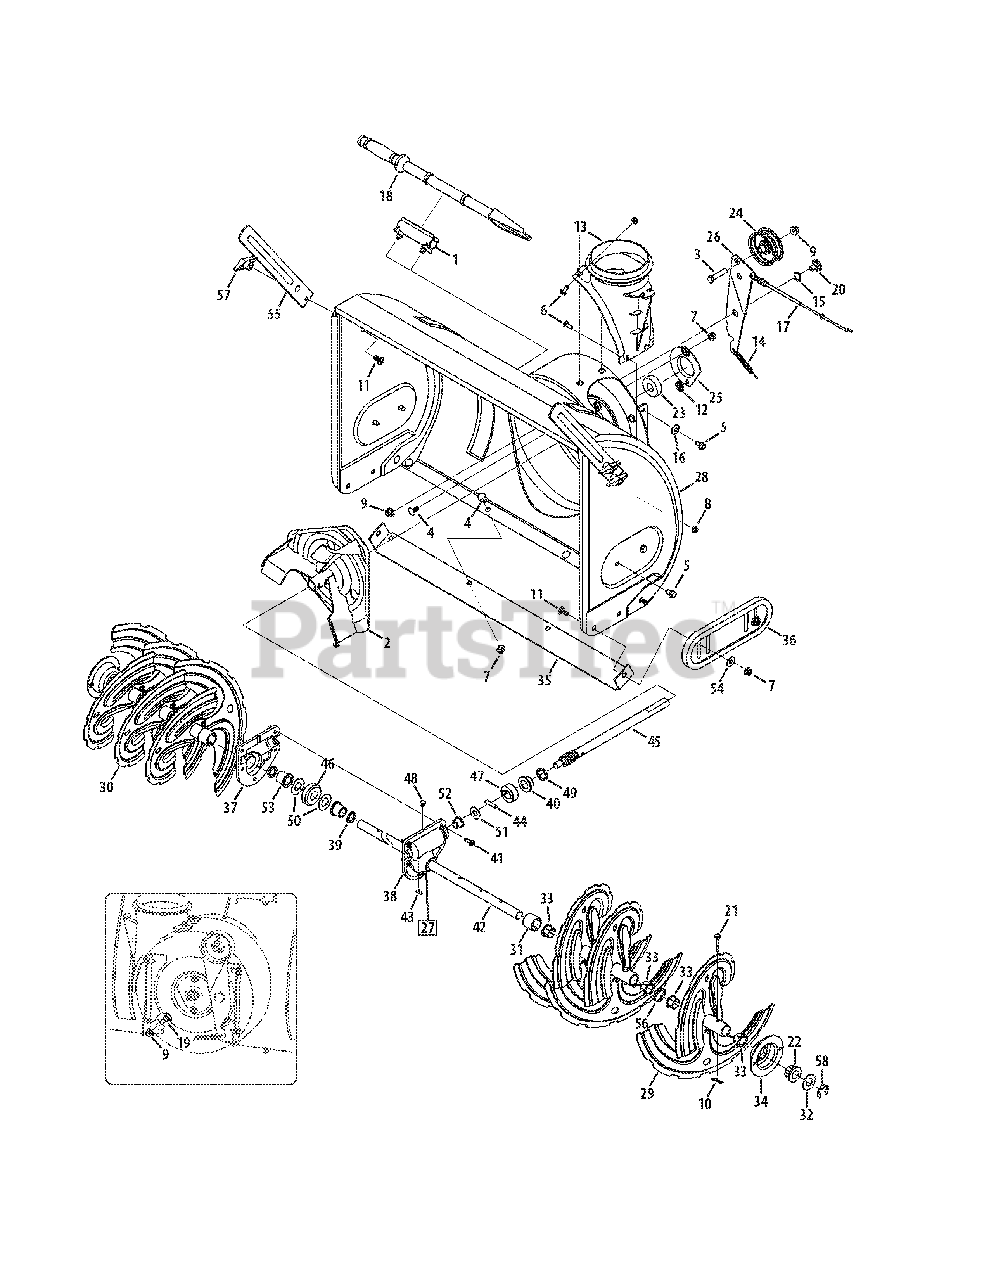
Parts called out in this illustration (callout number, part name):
1	Snow Removal Tool Mount
2	Impeller Assembly, 12" Dia.
3	Hex Screw, 3/8-16, 1.75, Gr5
4	Bolt, Carriage, 5/16-18, .750 Gr1
5	Screw, 5/16-18, 0.750
6	Screw, Carriage, 1/4-20, .750, Gr5
7	Nut, Flange Lock, 5/16-18, Nylon
8	Nut, Flange Lock, 1/4-20, Nylon
9	Nut, Flange Lock, 3/8-16, Nylon
10	Cotter Pin, Bow-tie
11	Scr., Crg., 5/16-18 x 1.00
12	Nut, Push-on, .25 Dia
13	Chute, Adapter 5" Dia
14	Spring, Extension, .38 OD x 4.59
15	Washer, Wave, .625 x .885 x .015
16	Washer, Bell, .340 x .872 x .060
17	Clutch Cable, Auger, 47.23"
18	Snow Removal Tool
19	Screw, Shoulder, .498 x .34, 3/8-16
20	Screw, Shoulder, .625 x .17, 3/8-16
21	Shear Pin, .25 x 1.50
22	Bearing, Hex Flange x .75 ID
23	Bearing, Ball, .75 ID x 1.85 OD
24	Flat Pulley, Idler, 2.75 OD
25	Housing, Bearing, 1.85 ID
26	Bracket, Auger Idler w/ Brake
27	Gearbox Assembly, Auger, 30"
28	Housing Assembly, Auger 30"
29	Spiral Assembly, LH
30	Spiral Assembly, RH
31	Spacer, 1.25 OD x .75 ID x 1.00
32	Washer, Flat, .76 x 1.49 x .06
33	Bushing, Flange, .80 ID x .91 OD
34	Housing, 1" Hex Bearing
35	Shave Plate, 2.25 x 29.66
36	Slide Shoe
37	Housing, Auger, RH Reduced
38	Housing, Auger, LH Reduced
39	Seal, Oil, .750 x 1.00 x .125
40	Bearing, Flange, .75 x 1.0 x .59
41	Screw, Self-tapping, 1/4-20, 0.750
42	Axle, Auger, 30"
43	Key, Hi-pro 3/16 x 5/8
44	Pin, Dowel, .25 OD x 1.2
45	Shaft, Worm .75 OD
46	Gear, Worm 20T
47	Collar, Thrust
48	Plug, 1/4 x .437
49	Seal, Oil, .75 x 1 x .131
50	Washer, Flat, .760 ID x 1.5 OD
51	Washer, Flat, .51 x 1.12
52	Bearing, Flange, .75 x 1.0 x .925
53	Bearing, Flange, .75 x 1.00 x .975
54	Washer, Flat, .349 x .879 x .063
55	Drift Cutter
56	Spacer, 1.25 OD x .75 ID x 3/16
57	Wing Nut
58	E-Ring
